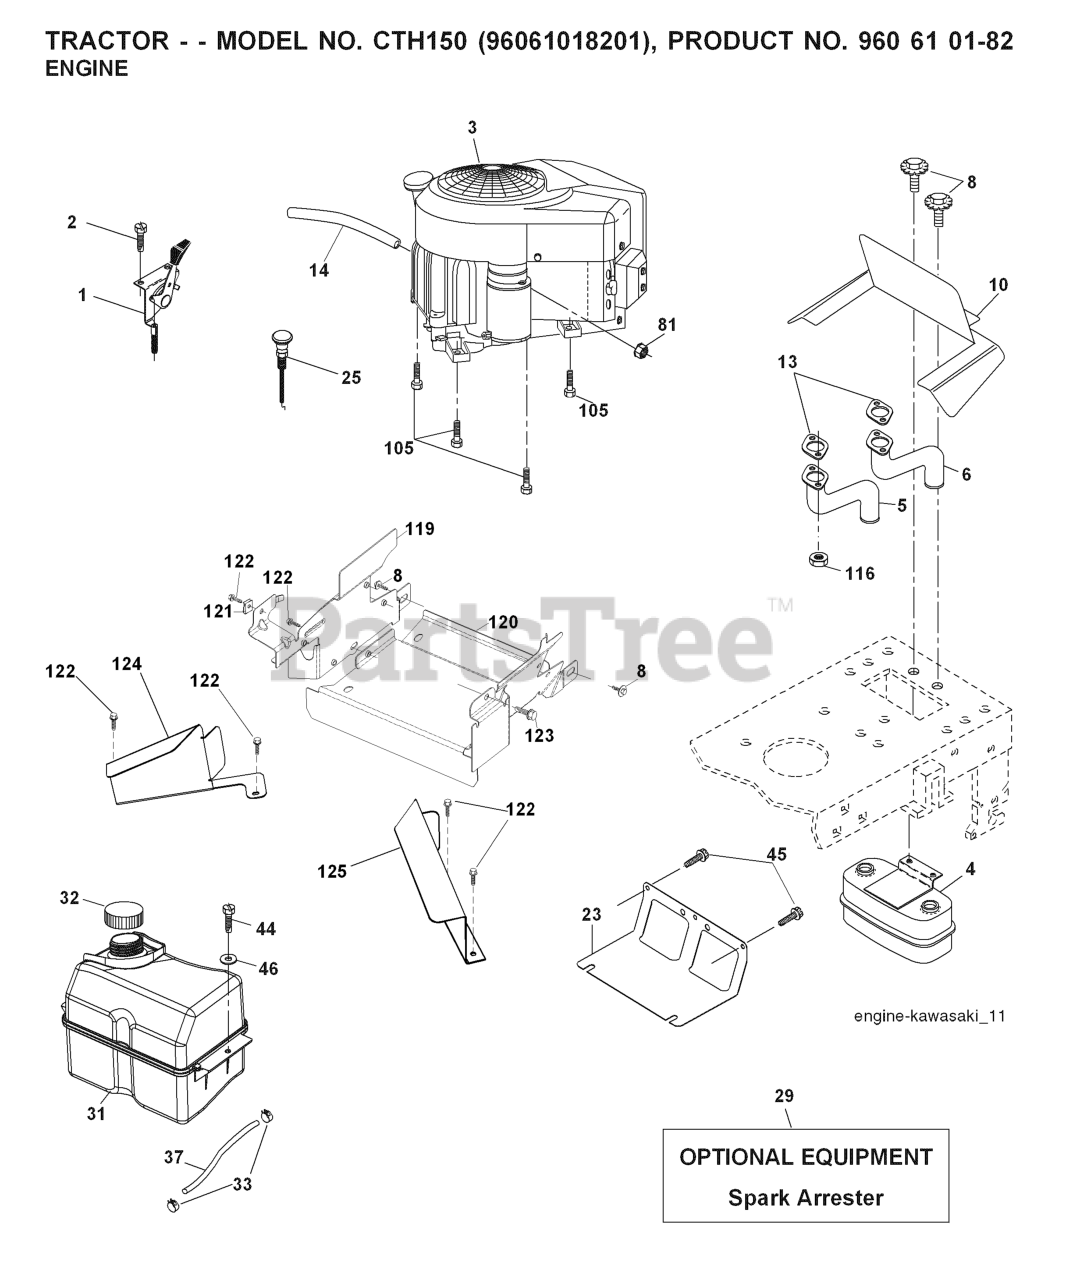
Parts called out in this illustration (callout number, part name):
1	THROTTLE CABLE
2	SCREW
4	MUFFLER.TWIN.CYL.LOW.TONE
5	EXHAUST TUBE LH KAWI
6	EXHAUST TUBE RH KAWI
8	BOLT.5/16-18UNCX3/4 W/SEMS.BLK
10	RP SHIELD HEAT MUFFLER
13	GASKET.EXHAUST.KAWASAKI.15-1
14	TUBE, DRAIN OIL ASM.
23	SHIELD.BROWNING.DBR.GUARD
25	CONTROL, CHOKE
29	KIT.SPARK ARRESTOR 794945 B&S
31	TANK.ASM.FUEL.FR.2.5GA.
32	FUEL CAP
33	HOSE CLAMP
37	LINE.FUEL.20
44	SCREW HEXWSHR 1/4-20X3/4
45	SCREW, 3/8-16X3/4
81	NUT
105	SCREW 3/8-16X1
116	NUT.HEX.FLANGE.TOPLOCK
119	LENKRAD
120	GUARD 532199767
122	SCREW.1/4-20X5/8
123	SCREW, 5/16-18 X 1/2
